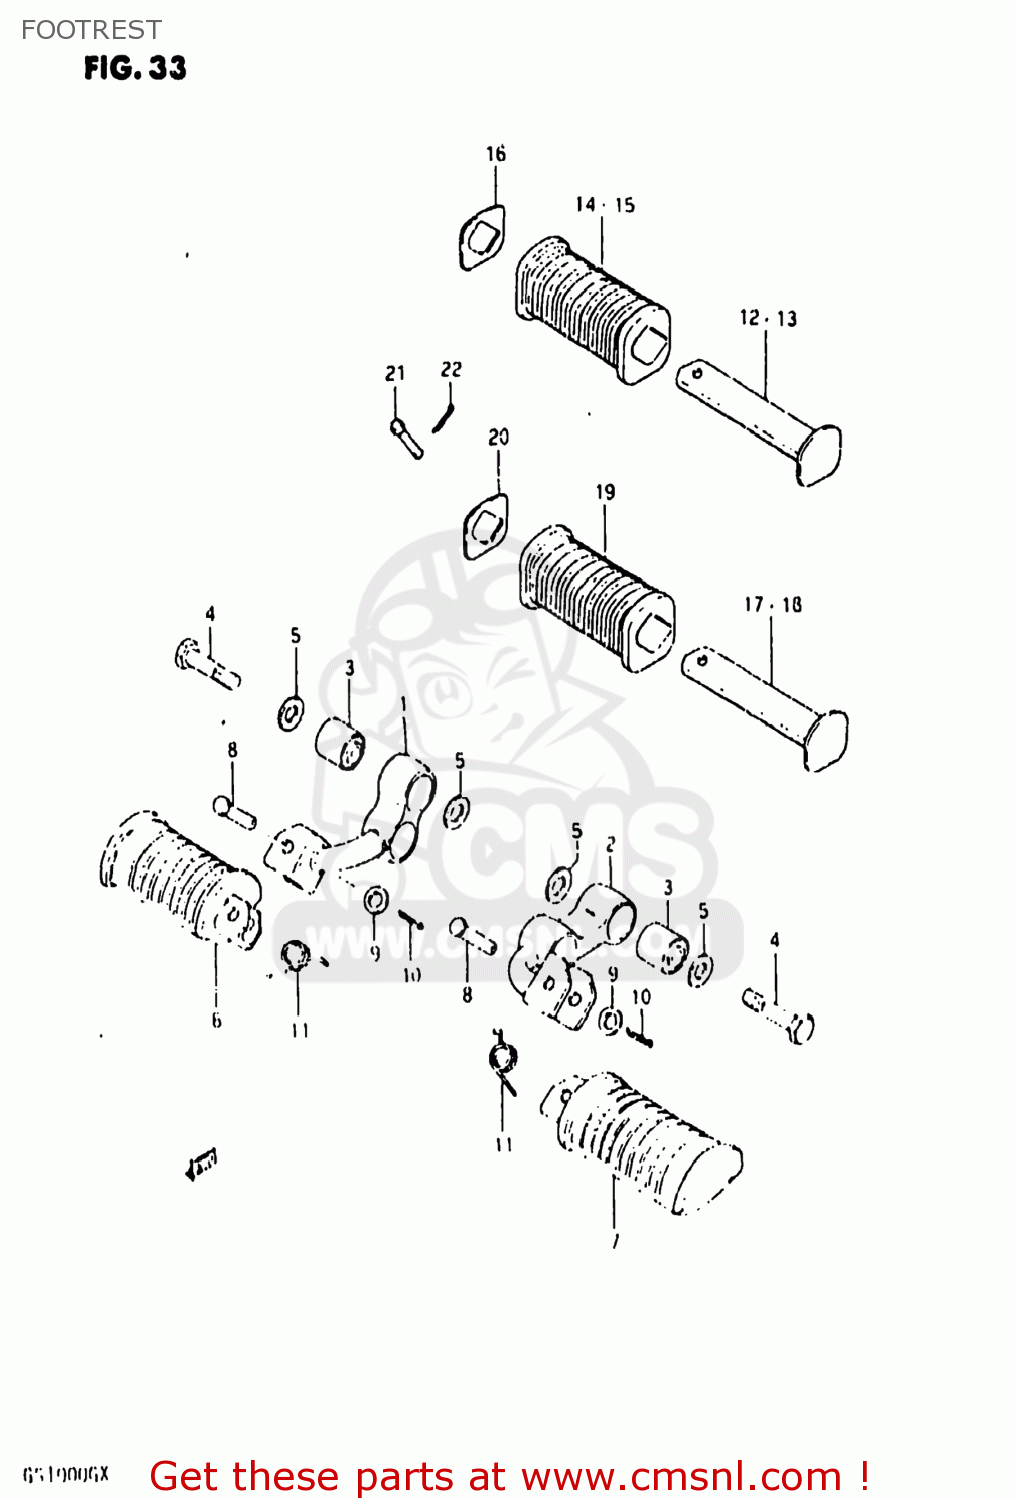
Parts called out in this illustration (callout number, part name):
1	BAR,FRONT FOOTREST,RIGHT
2	BAR,FRONT FOOTREST,LEFT
3	BUSH
4	BOLT
5	WASHER (10.1X21X2.3)
6	RUBBER,FRONT FOOTREST
7	FOOTREST
8	PIN
9	WASHER
10	PIN
11	SPRING
12	BAR,REAR FOOTREST
13	BAR,REAR FOOTREST
14	RUBBER,PILLION FOOTREST
15	RUBBER, LH
16	WASHER,REAR FOOTREST RUBBER
17	BAR,REAR FOOTREST,RIGHT
18	BAR,REAR FOOTREST,LEFT
19	RUBBER,PILLION FOOTREST
20	WASHER,PILLION FOOTREST RUBBER
21	PIN
22	PIN
